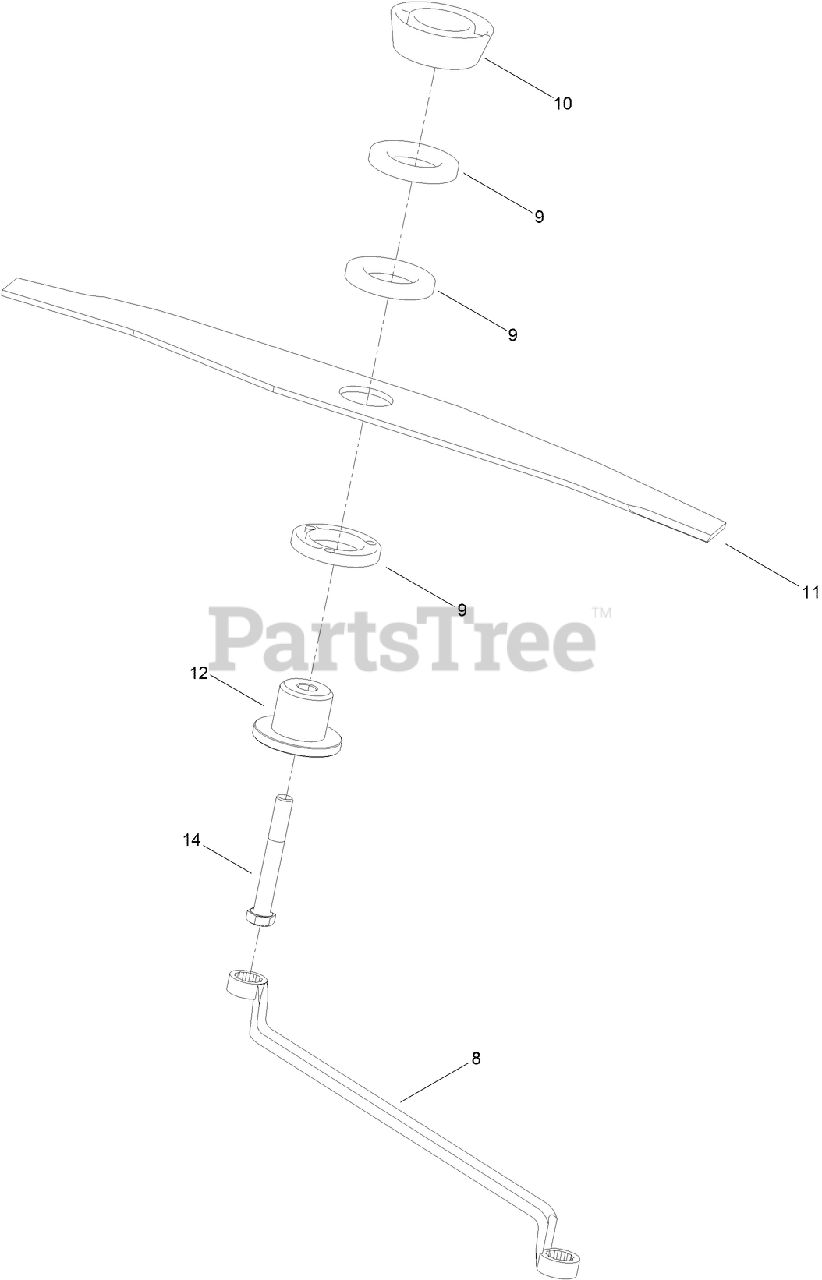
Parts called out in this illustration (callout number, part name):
8	SPANNER
9	SPACER-BLADE, ALUMINIUM
10	SPACER-DISTANCE
11	BLADE-46 CM
12	RETAINER-BLADE
14	SCREW-SET
